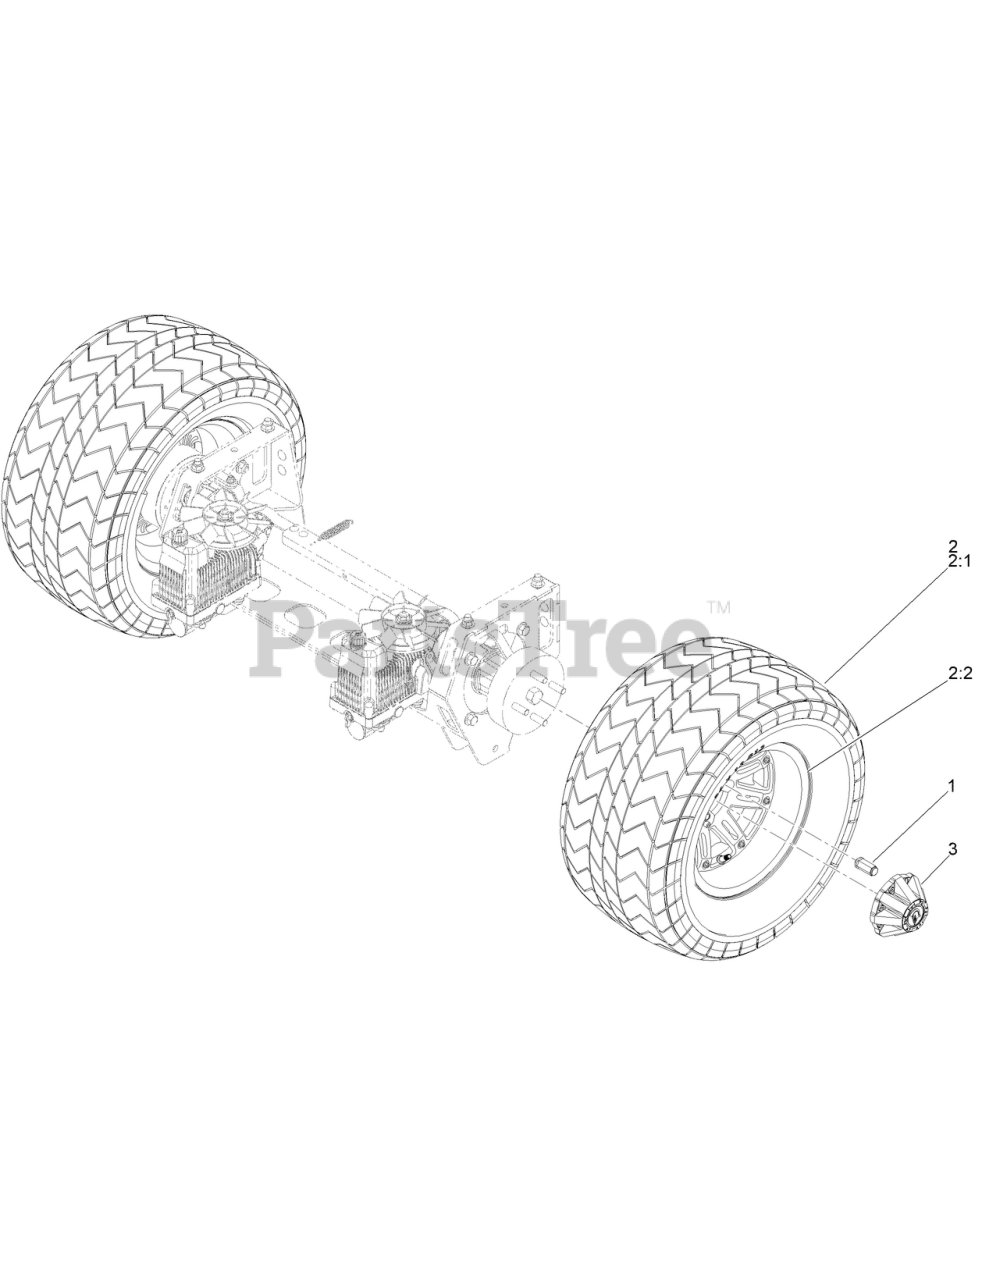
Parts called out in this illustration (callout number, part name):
1	LUG NUTS
2	WHEEL AND TIRE ASM
2:1	24X 12 X 12 SOFT RIDE RADIAL TIRE ONLY
3	CENTER CAP- SPARTAN
